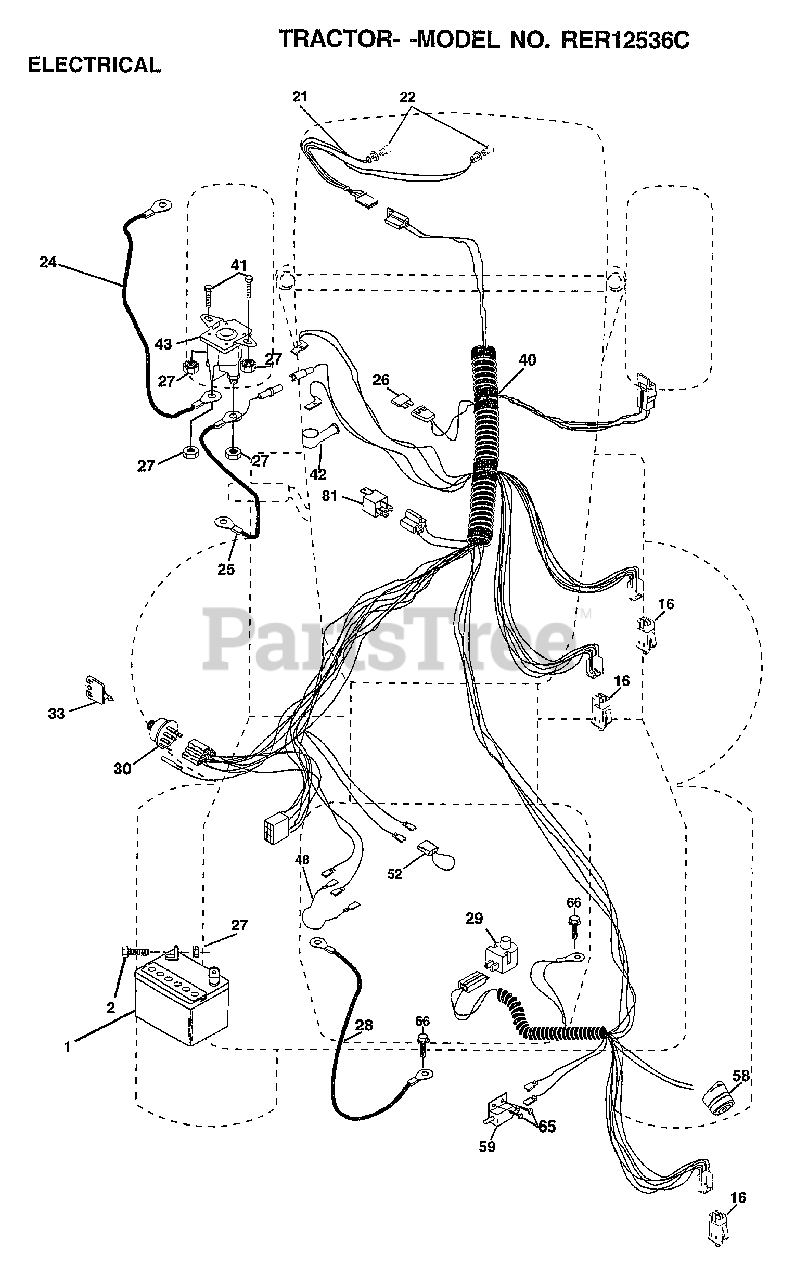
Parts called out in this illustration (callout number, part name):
2	BOLT LT
16	SWITCH INTERLOCK
21	HARNESS.ASM.LIGHT W/4152J
22	HEADLAMP BULB
24	"CABLE T, BATTERY"
25	CABLE.BATTERY.CRD
26	FUSE.15 AMP
27	NUT
28	"CABLE.GRD.6GA/18""BLACK"
29	SWITCH.PLUNGER
30	SWITCH.IGN.
33	KEY MLD GEN DELTA
40	HARNESS IGN CORD
41	BOLT HXHD FIN
48	ADAPTER AMMETER
52	PROTECTION LOOP
58	BUZZER CRD
59	SWITCH.FBI.CRD
65	SCREW
66	SCREW LT
81	RELAY ASSY T
